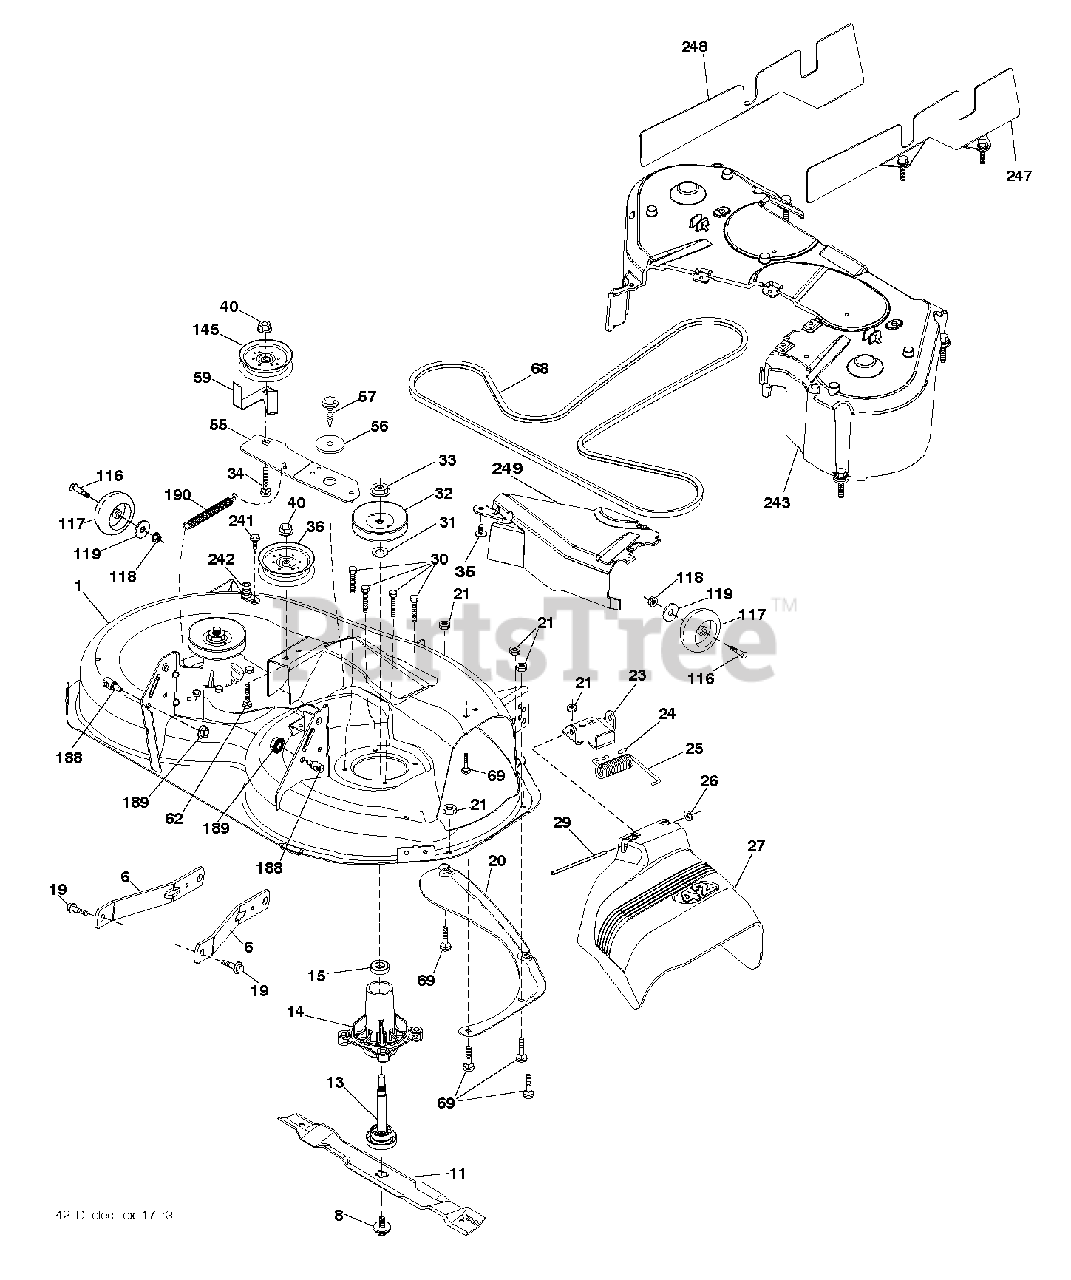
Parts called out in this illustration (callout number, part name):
6	ARM.SUSPENSION.MOWER.R
8	BOLT.WASHER.ASM.7/16-2
11	42" HI-LIFT BLADE
13	SHAFT.ASM.MDRL.N/GREASE.38
14	HOUSING.MANDREL.4PT.
19	BOLT.SHOULDER
20	BAFFLE.VORTEX
21	LOCKNUT
23	BRKT.DEFLECTOR.38"2005+
24	CAP-SLEEVE LT
25	SPRING.TORSION.DEFLECT
26	NUT PUSH M
27	DEFLECTOR ASM.42"TEX.FRENCH
29	ROD.HINGE
30	SCREW, WASHER HEAD
31	WASHER.SPACER.MANDREL
32	PULLEY/MANDREL
33	NUT.FLANGE.LOCK.TOP
34	BOLT.3/8-16X1.50
35	FASTENER.XMAS.TREE
36	PULLEY.IDLER.2006
40	NUT LOCK FLG 3/8-16 UNC
55	IDLER.ARM.42"
56	SPACER.RETAINER
57	SCREW 3/8-16X1
59	GUARD, BELT
68	BELT V SECONDARY
69	BOLT
116	BOLT M
117	WHEEL.GAGE.HALF.SPOKED
118	NUT LOCK FLG 3/8-16 UNC
119	WASHER
145	PULLEY.IDLER.48"PRIMARY
188	STUD.FASTNER.W/ANTI-ROTATE
189	NUT LOCK HEX FLANGE 5/16-18
190	SPRING.MOWER.DRIVE.ELECTRIC
241	SCREW.TT.#10-32X.5.3/8.FLANGE
242	PORT.WASHOUT
243	COVER DECK
247	SHIELD DECK RIGHT
248	SHIELD DECK LEFT
249	COVER CABLE CLUTCH
